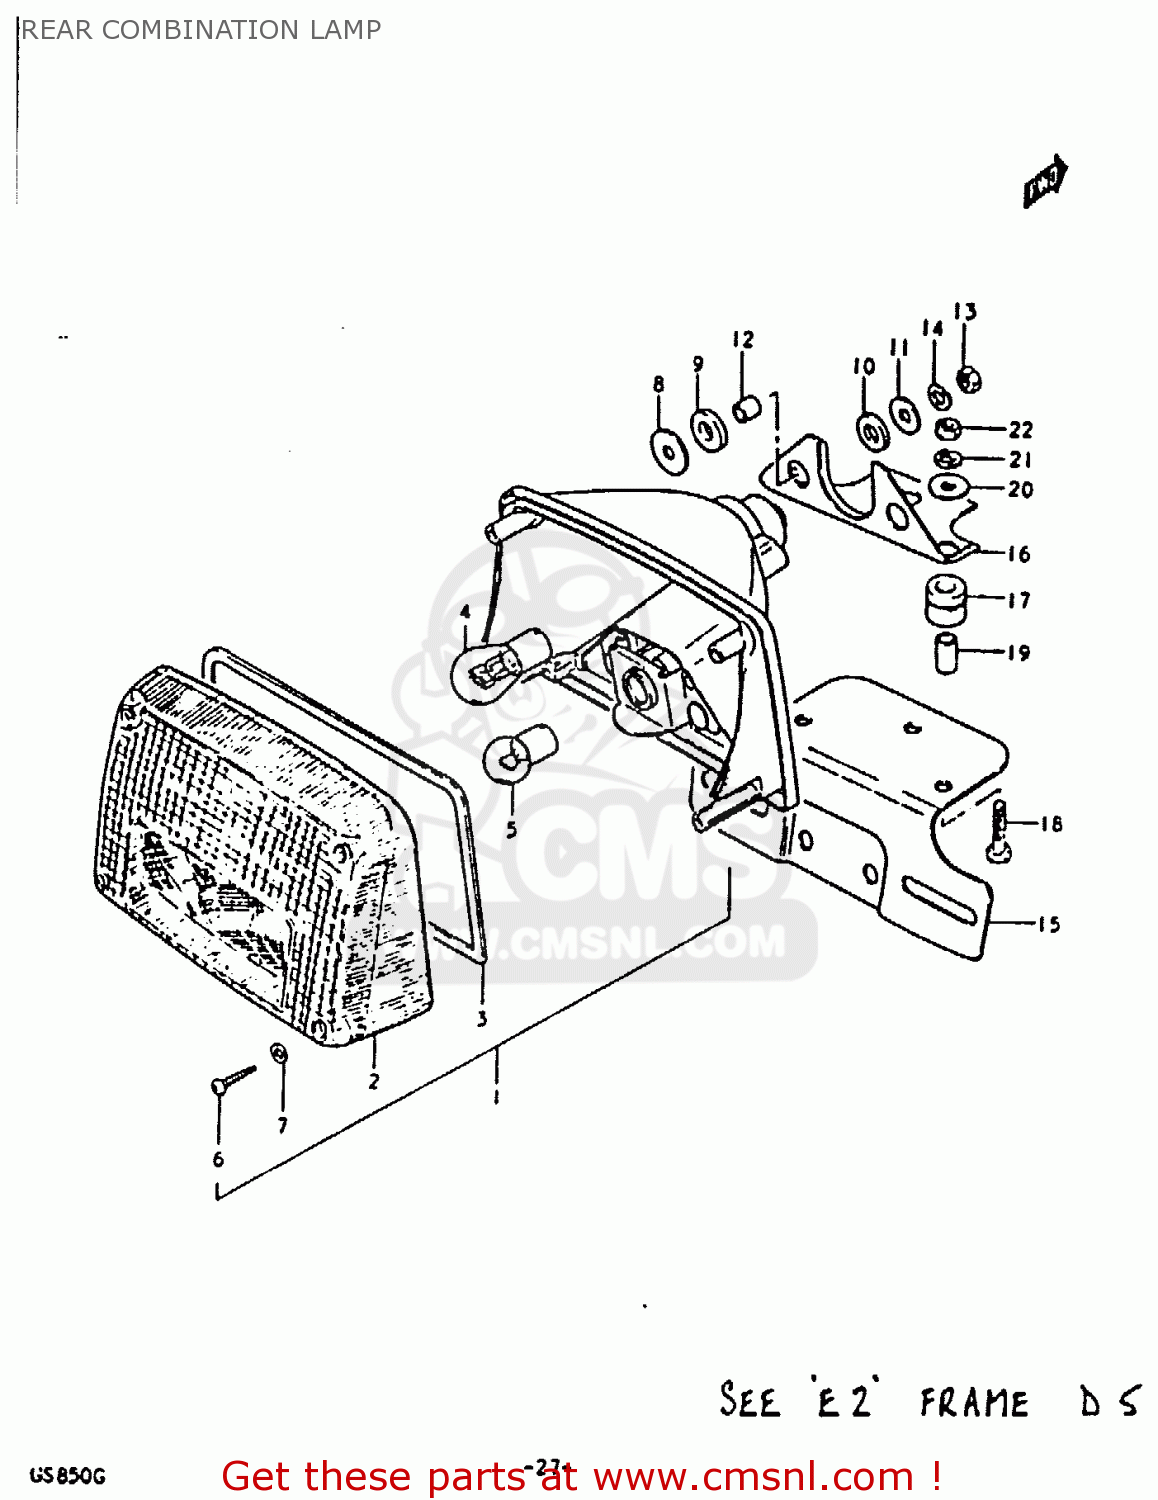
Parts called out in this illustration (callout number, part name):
1	LAMP ASSEMBLY,REAR COMBINATION
2	LENS
3	GASKET (NAS)
4	BULB(12V23W)
5	BULB
6	SCREW
7	GASKET (NAS)
8	WASHER
9	CUSHION
10	CUSHION
11	WASHER (6.5X24X1.6)
12	SPACER(6.1X9X7.5)
13	NUT
14	LOCK WASHER
15	PLATE, LICENSE
16	BRACKET,LICENSE PLATE
17	CUSHION, BRACKET
18	BOLT
19	SPACER (6.1X8X15.5)
20	WASHER
21	LOCK WASHER
22	NUT
